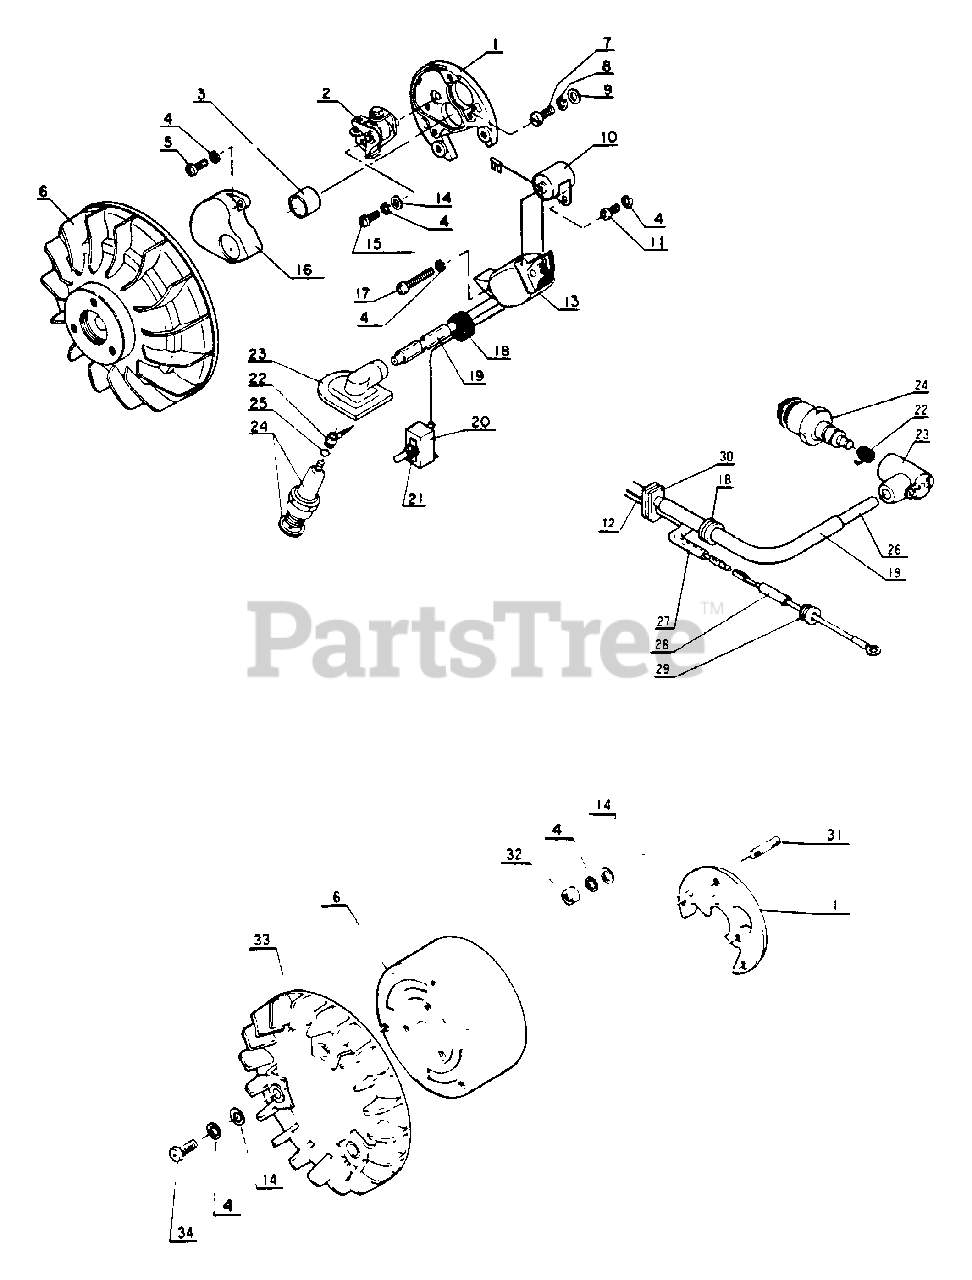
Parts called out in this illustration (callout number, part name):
1	CONTACT POINT SET
2	ARM, BREAKER
3	CAM
4	WASHER, SPRING 4 MM
5	SCREW - 4×12
6	FLYWHEEL
7	SCREW - 5×14
8	WASHER, SPRING 5
9	WASHER, FLAT 5.5×10×0.8
10	CONDENSER
11	SCREW - 4×8
13	COIL, IGNITION
14	WASHER 4 MM
15	SCREW - 4×8
16	COVER
17	SCREW - 4×22
19	TUBE, INSULATOR
20	SWITCH, IGNITION
21	CAP
22	TERMINAL, SPARK PLUG CAP
23	CAP, SPARK PLUG
24	SPARK PLUG - BM6A
26	LEAD, SPARK PLUG
27	TUBE
28	LEAD - GROUND
29	GROMMET
30	BUSHING
31	STUD
32	NUT
33	FAN
34	SCREW
